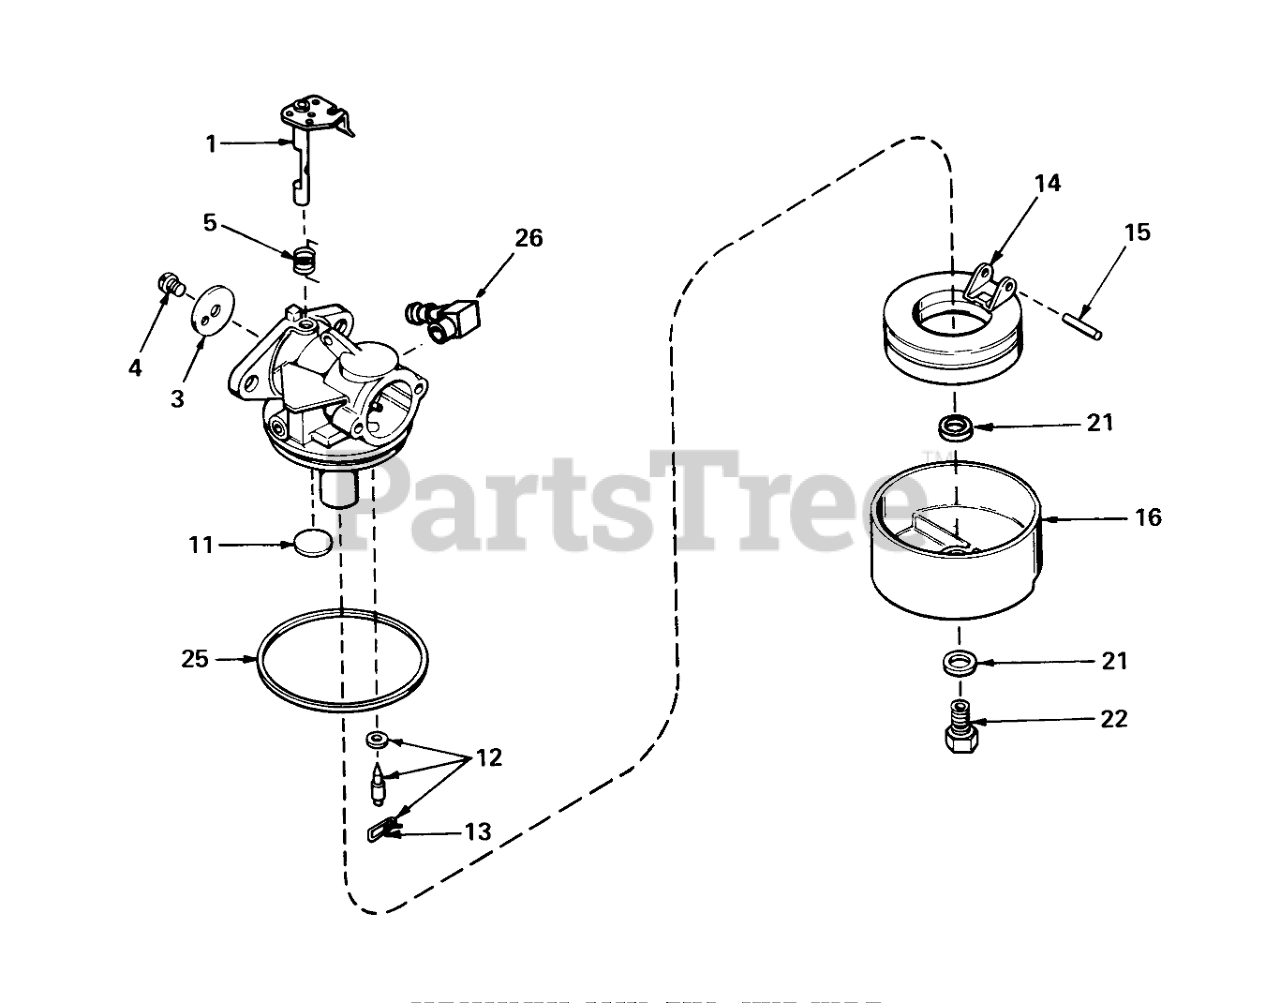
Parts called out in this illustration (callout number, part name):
1	Throttle Shaft and Lever ASM
3	Throttle-Shutter
4	Screw-Shutter
5	Spring, Return
11	Plug-Welch, Atmospheric Vent
12	Inlet Needle, Seat & Clip Assy. (Incl. No. 13)
13	Clip-Spring
14	Float,Carburetor
15	Shaft-Float
16	Bowl Float
21	Gasket-Bowl
22	Nut-Float Bowl
25	O Ring-Bowl, Float
26	Fitting-Fuel
